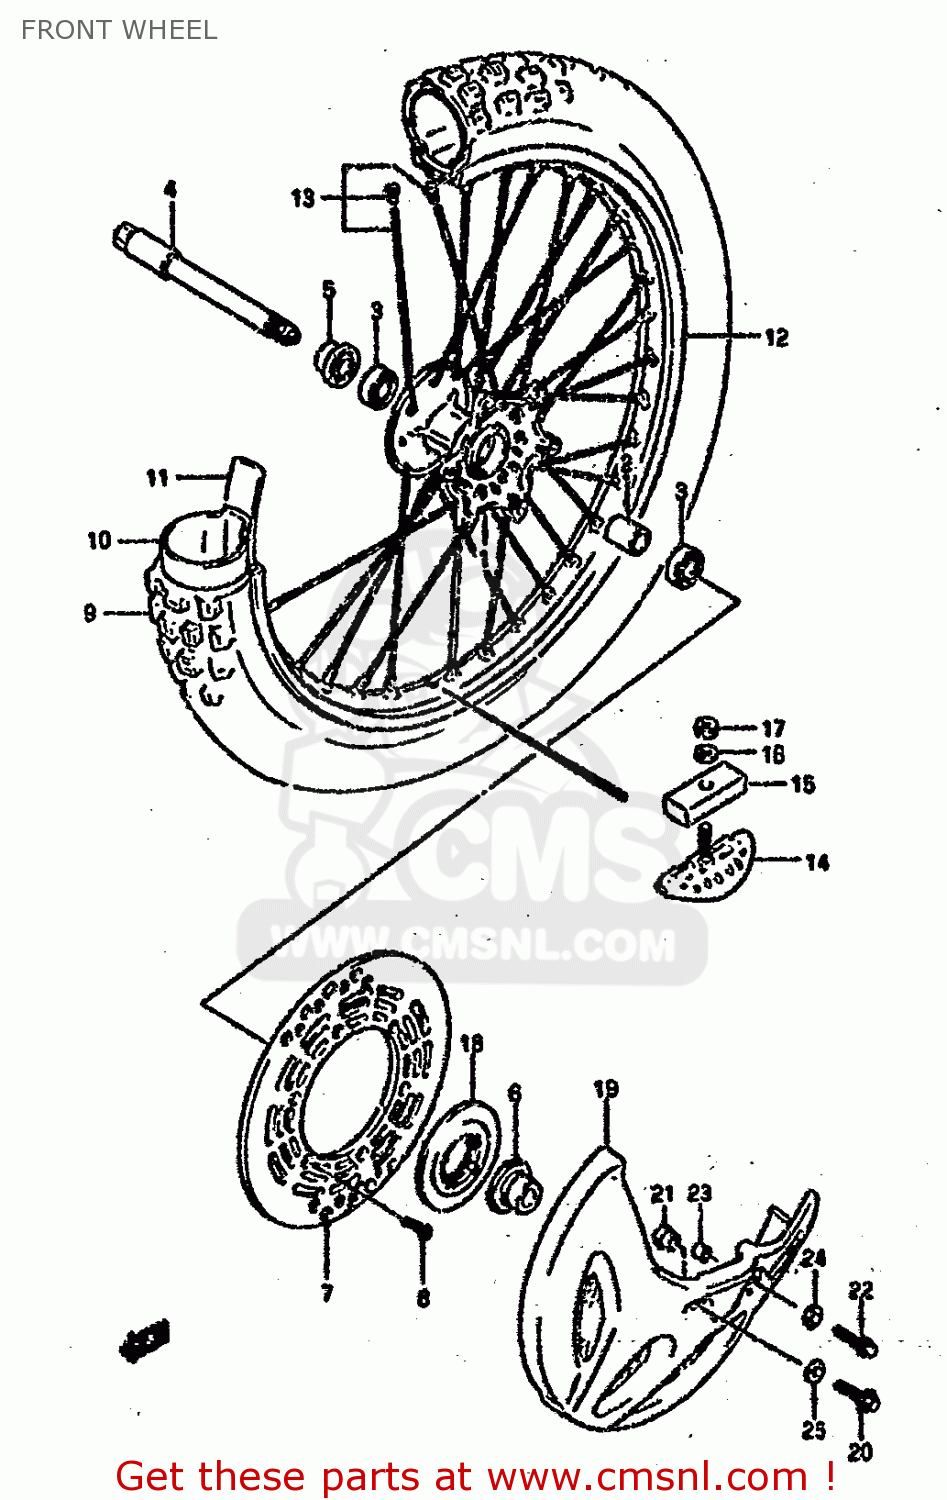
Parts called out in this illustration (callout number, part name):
1	HUB,FRONT
2	SPACER,FRONT HUB BEARING
3	BEARING
4	AXLE,FR
5	SPACER,FR AXLE,R
6	SPACER,FRONT AXLE,LEFT
7	DISC,FR BRAKE
8	SCREW,BRAKE DISC
9	TIRE,FRONT
10	TUBE
11	PROTECTOR,WHEEL INNER
12	RIM,FRONT WHEEL (1.60X2
13	SPOKE SET,FR WHEEL
14	STOPPER,BEAD
15	CUSHION,BEAD STOPPER
16	WASHER
17	NUT
18	CAP,FR HUB,L
19	COVER,FR BRAKE DISC
20	BOLT
21	WASHER (8.5X16X1.6)
22	BOLT
23	SPACER(6.1X8X14.5)
24	WASHER(6.5X18X1)
25	WASHER(8.5X18X1)
